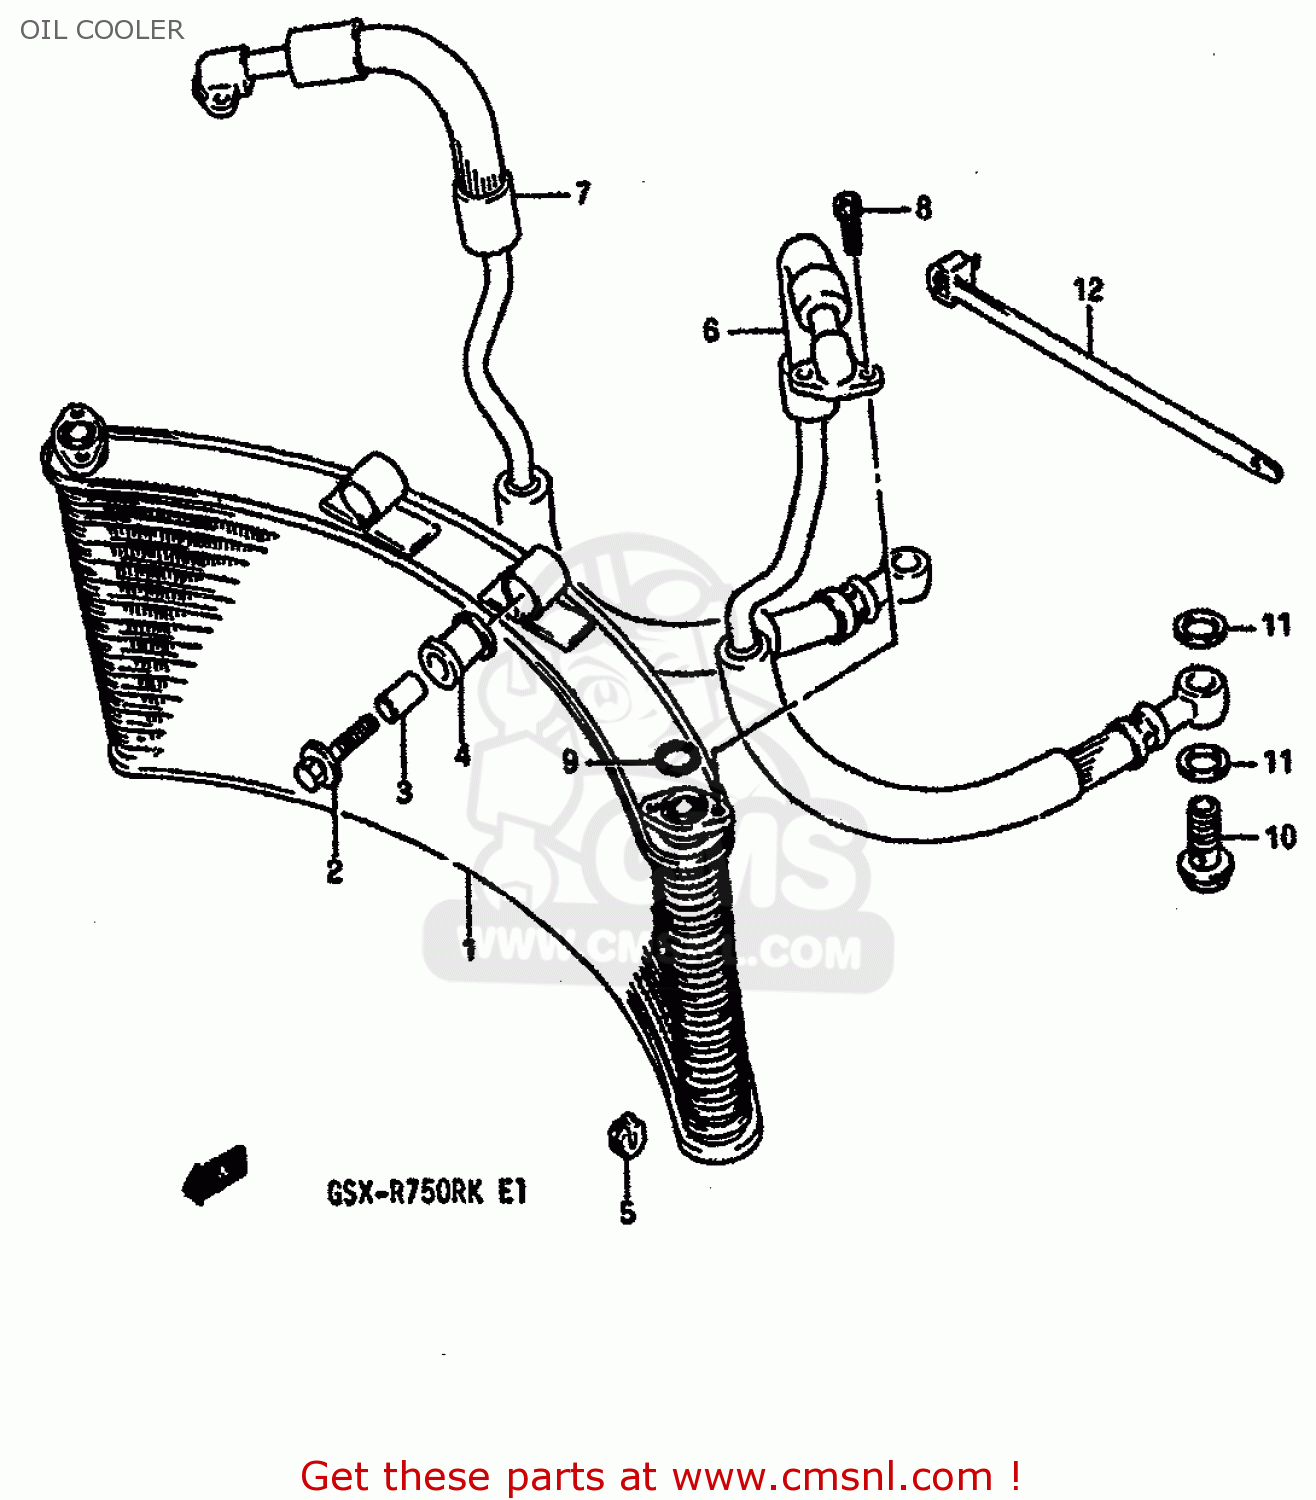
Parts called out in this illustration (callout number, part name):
1	COOLER ASSY,OIL
2	BOLT(8X40)
3	SPACER (8.8X12X24.5)
4	CUSHION,OIL COOLER NO.1
5	CUSHION,OIL COOLER NO.2
6	HOSE,OIL CONTROL,L
7	HOSE,OIL COOLER RH
8	BOLT
9	O RING(D:2.4,ID:12.3)
10	BOLT UNION
11	GASKET(16X22X2) (NAS)
12	CLAMP
